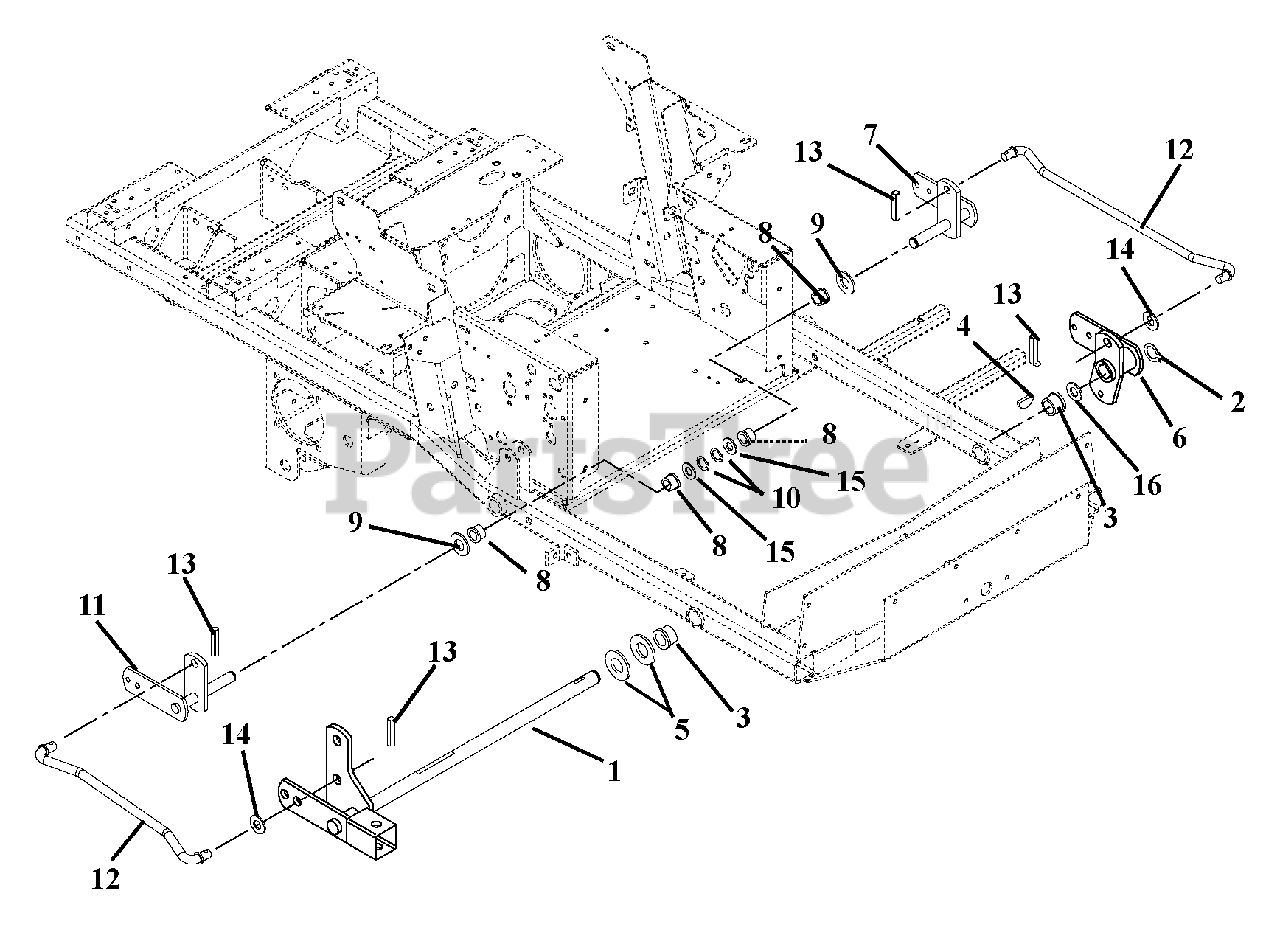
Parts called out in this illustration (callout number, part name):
1	Lift, Mower
2	Ring, Retaining External 1.00 x .078
3	Bushing, Flange 1.00 x 1.12 x .75 x 1.375
4	Key, Woodruff .25 x 1.00
5	Washer, Flat Steel 1.062 x 2.00 x .134
6	Weldment, Lift Arm-Front
7	Weldment, Rear Lift Arm-Left Hand
8	Bushing, Flange Nylon .762 x 1.0 x .58 x 1.48
9	Washer, Hardened Steel .758 x 1.23 x .031
10	Ring-Retaining-External .689 x .077
11	Weldment, Rear Lift Arm- Right Hand
12	Rod, Lift Assist 19.35"
13	Pin, Roll .25 x 1.25 Stainless Steel
14	Washer, Flat Steel .630 x 1.25 x .062
15	Washer, Flat Steel .755 x 1.25 x .125
16	Washer, Hardened Thrust 1.00 x 1.55 x .03
